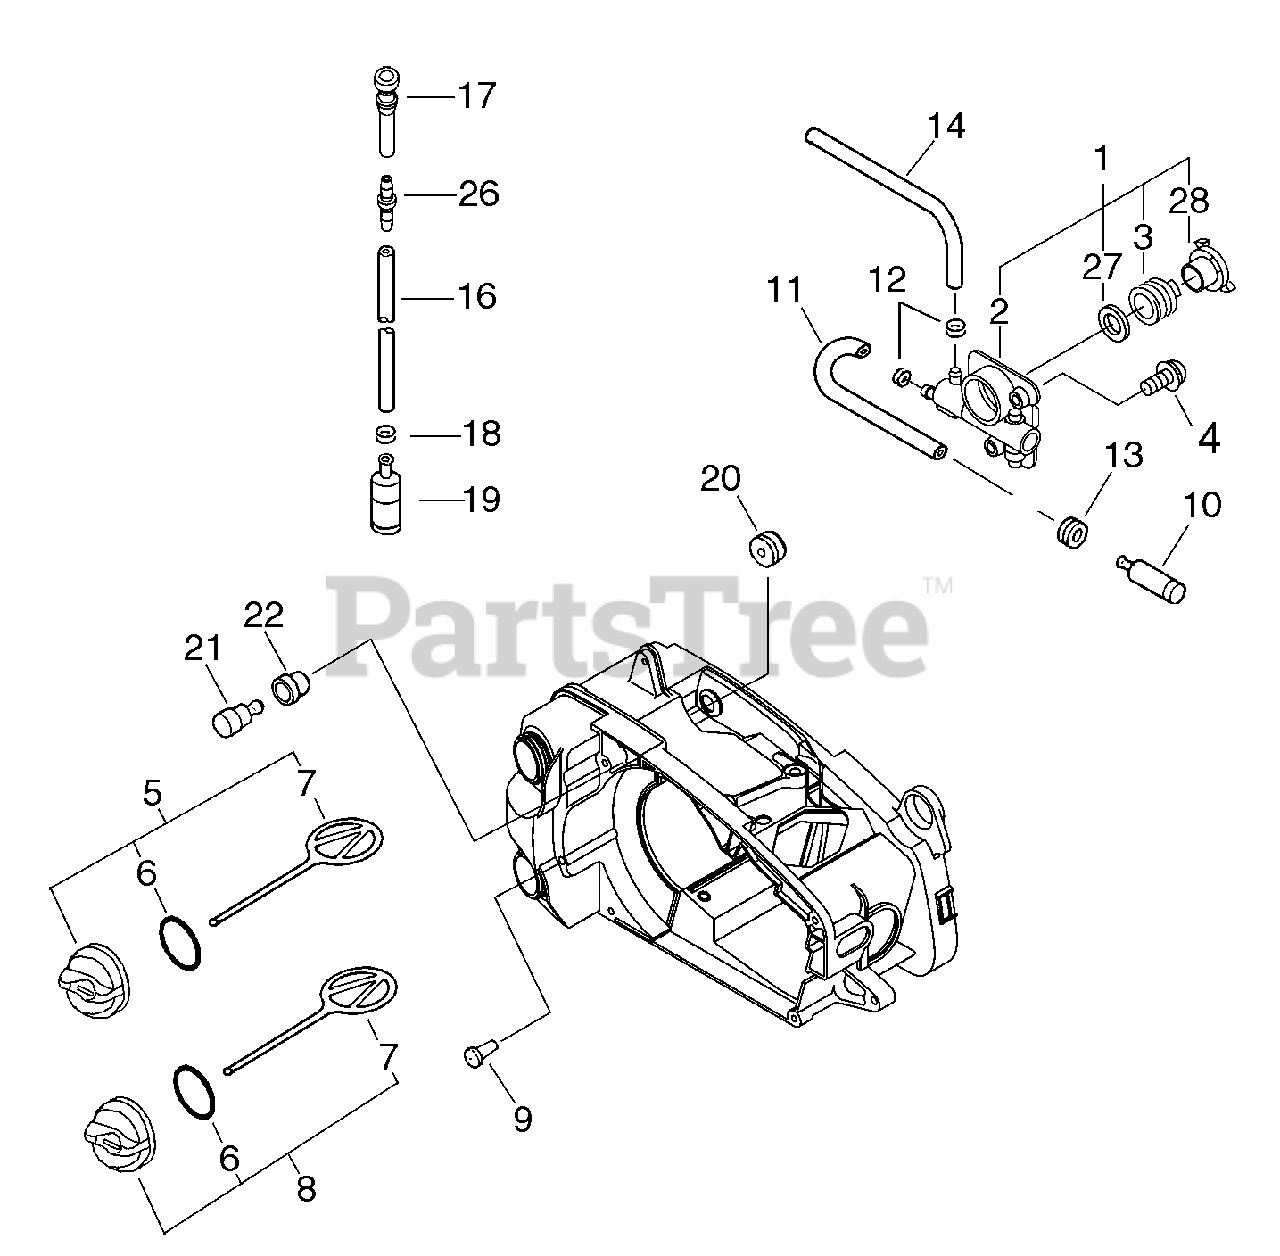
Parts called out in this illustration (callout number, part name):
1	AUTO-OILER ASSY
2	AUTO-OILER ASSY
3	GEAR - WORM
4	SCREW - 4X12
5	CAP ASSY - ORANGE
6	O-RING - 18
7	CONNECTOR, CAP
8	CAP ASSY - BLACK
9	VENT, TANK
10	FILTER, OIL
11	PIPE
12	CLIP - 6.5
13	GROMMET
14	PIPE - 3X6X90 -- BLACK
16	PIPE
17	PIPE - FUEL
18	CLIP - 6
19	FILTER, FUEL
20	GROMMET
21	VENT, FUEL TANK
22	GROMMET
26	CONNECTOR, PIPE
27	WASHER - 11
28	COLLAR - 10
